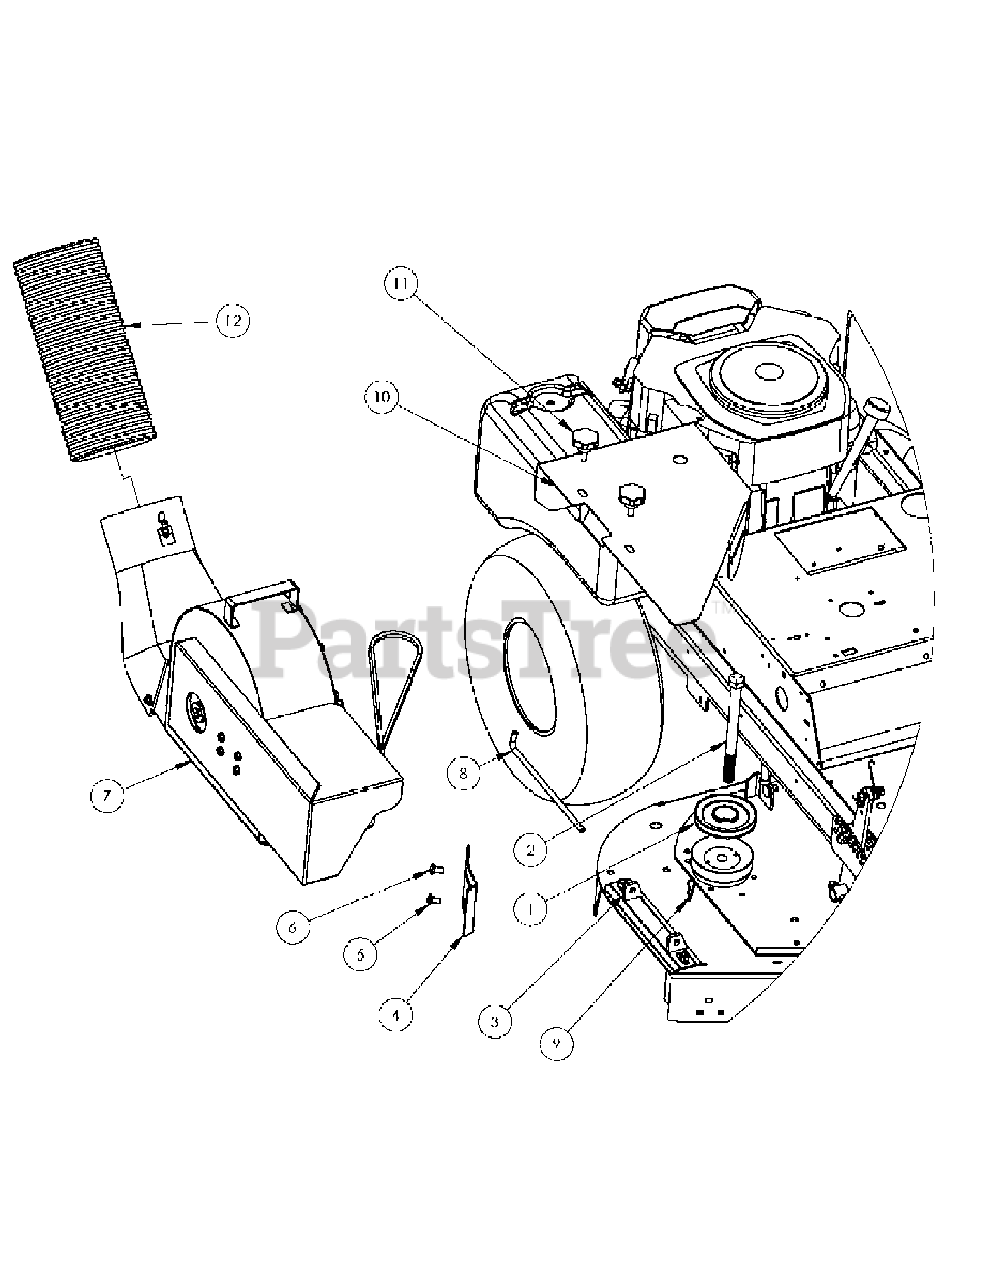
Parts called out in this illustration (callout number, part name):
1	BLOWER DRIVE PULLEY
2	EXISTING BOLT
3	DECK BRACKET
4	DECK SLIDE ADAPTOR
5	EXISTING BOLT
6	CARRAGE BOLT, 3/8" - 16 X 1" LONG
7	15" BLOWER
8	MOUNTING PIN
10	48" BELT GUARD
10	60" BELT GUARD
11	MOUNTING KNOBS
12	DISCHARGE HOSE
